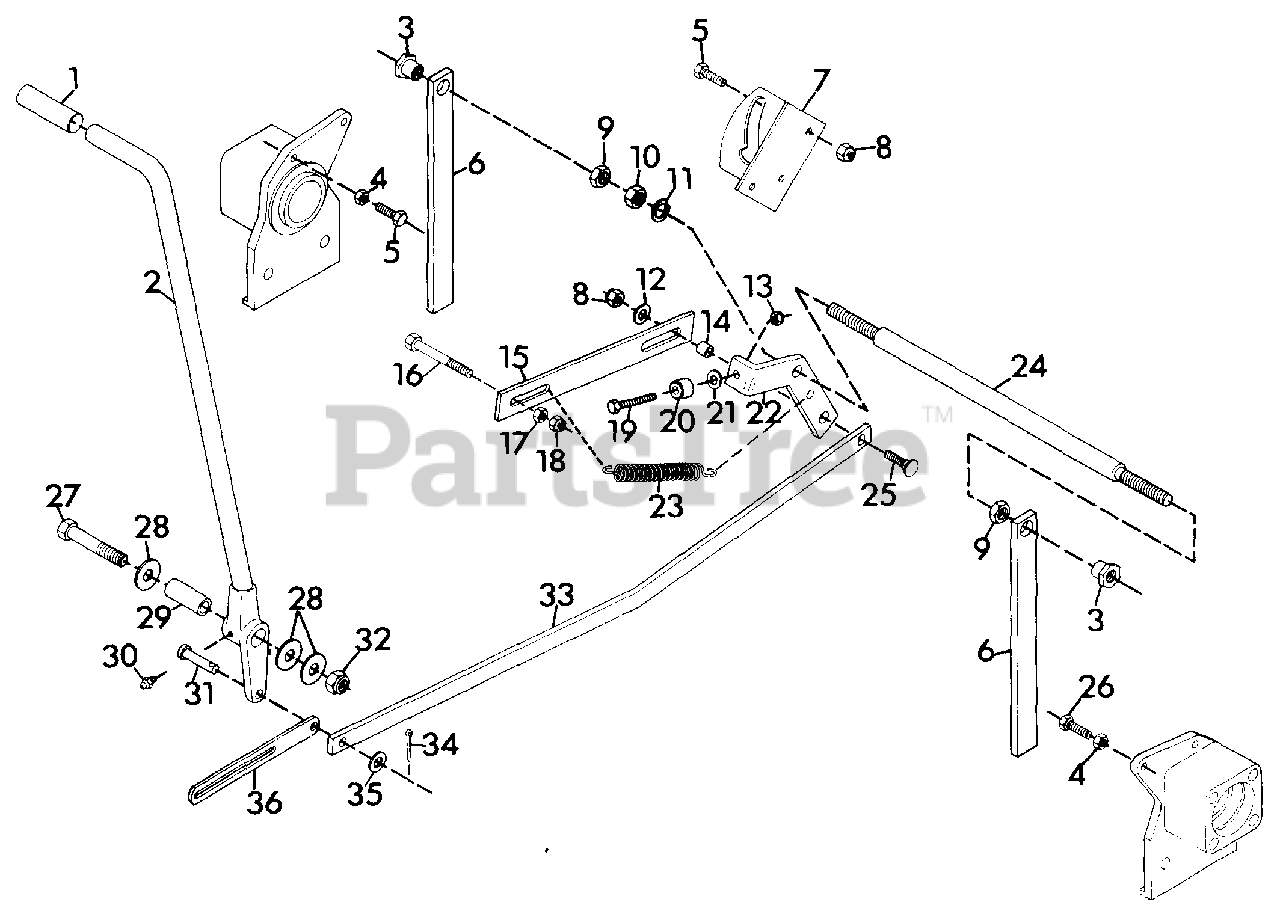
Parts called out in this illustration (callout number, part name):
1	GRIP, HANDLE
2	LEVER, FWD-REV
3	BUSHING, FWD-REV SLIDE ROD
4	NUT, HEX 5/16-18
5	BOLT, HEX 5/16-18X1.00
6	SPRING, FWD-REV CLUTCH
7	WELDMENT, FWD-REV ACTUATING
8	NUT, LOCK 5/16-18
9	NUT, JAM 1/2-13 HEX
10	NUT, HEX 1/2-13
11	WASHER, LOCK 1/2 SP HEAVY
12	WASHER, FLAT .313X.875X.065
13	NUT, LOCK 1/4-28
14	BUSHING, FWD-REV LINKAGE
15	STRAP, NEUTRAL DETENT
16	BOLT, HEX 3/8-16X3.00
17	NUT, HEX 3/8-16
18	NUT, LOCK 3/8-16
19	BOLT, HEX 1/4-28X1.38 GR. 8
20	ROLLER, CLUTCH CAM
21	WASHER, FLAT .281X.625X.065
22	ARM, FWD-REV CLUTCH ROLL
23	SPRING, NEUTRAL DETENT
24	ROD, FWD-REV SLIDE
25	BOLT, 5/16-18X1.25 RD HD SQ NK
26	BOLT, HEX 5/16-18X1.25
27	BOLT, HEX 1/2-13X2.75
28	WASHER, FLAT .563X1.375X.109
29	BUSHING, .505X.74X1.438
30	FITTING, LUBE 1/4-28
31	PIN, CLEVIS .375X.948
32	NUT, LOCK 1/2-13
33	LINK, FWD-REV SHIFTER
34	PIN, COTTER .09X.75
35	WASHER, FLAT .406X.812X.065
36	STRAP, NEUTRAL RETURN
